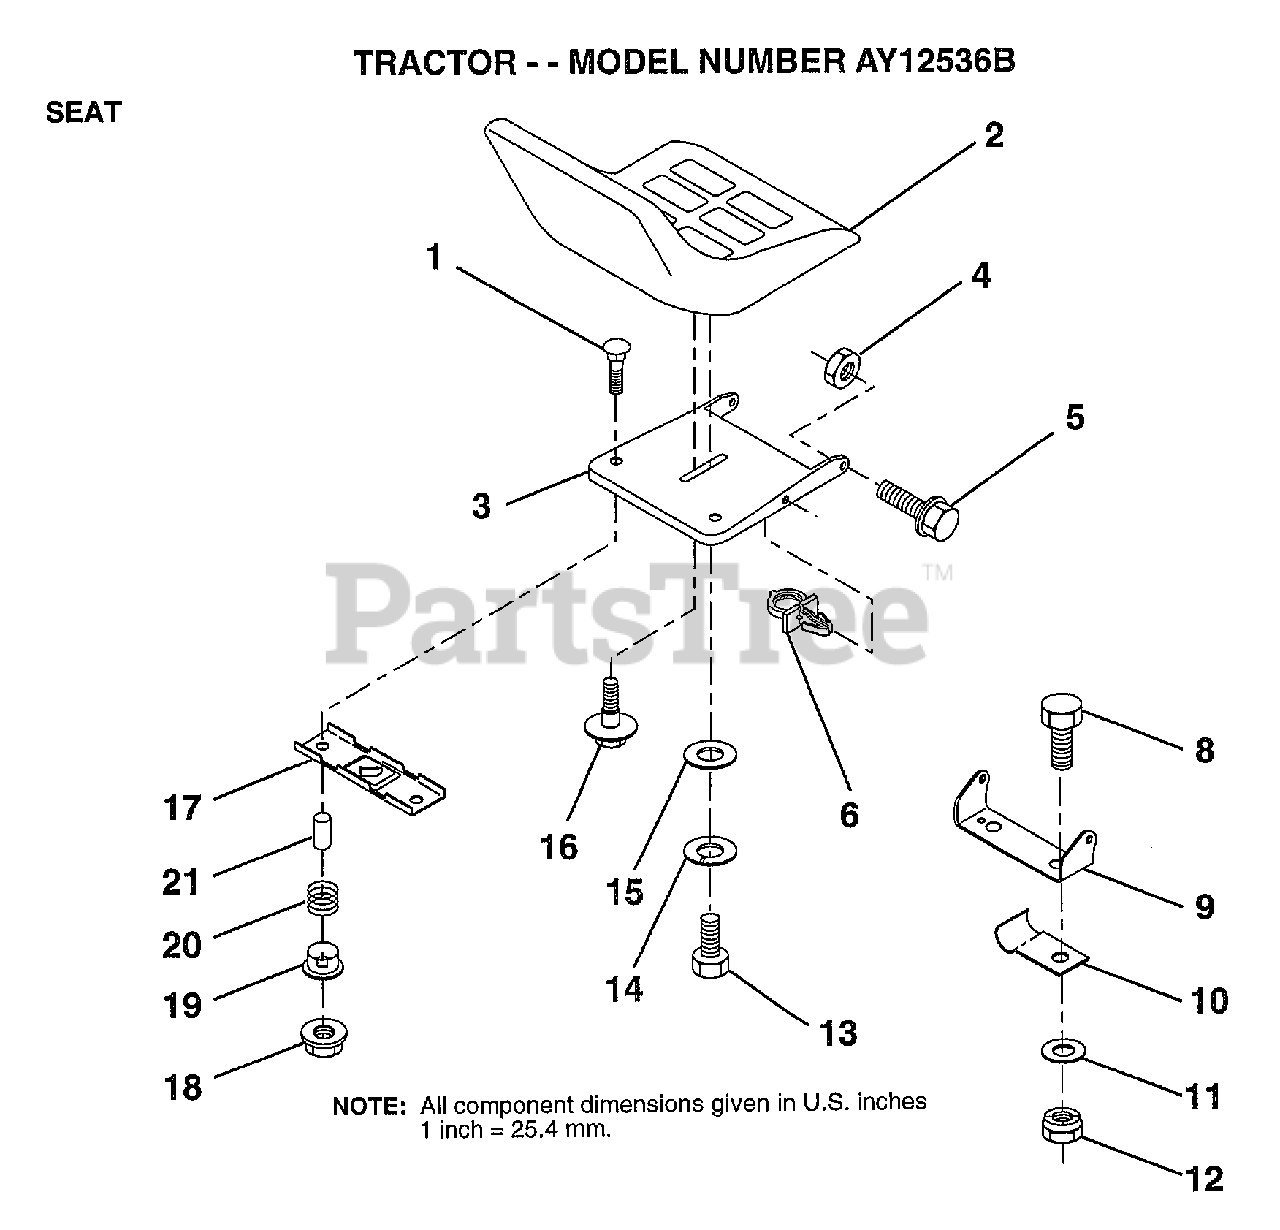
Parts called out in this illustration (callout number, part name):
4	NUT
5	BOLT.SHLD.5/16-18
6	CLIP.PUSH-IN.HING
8	BOLT
9	BRACKET PVT SEAT
10	"CLIP,INSULATOR"
11	WASHER
12	NUT
13	BOLT
14	LOCKWASHER
15	WASHER
16	"BOLT,SHOULDER"
17	BRKT SWITCH
19	BUSHING
20	SPRING
21	SPLIT SPACER
